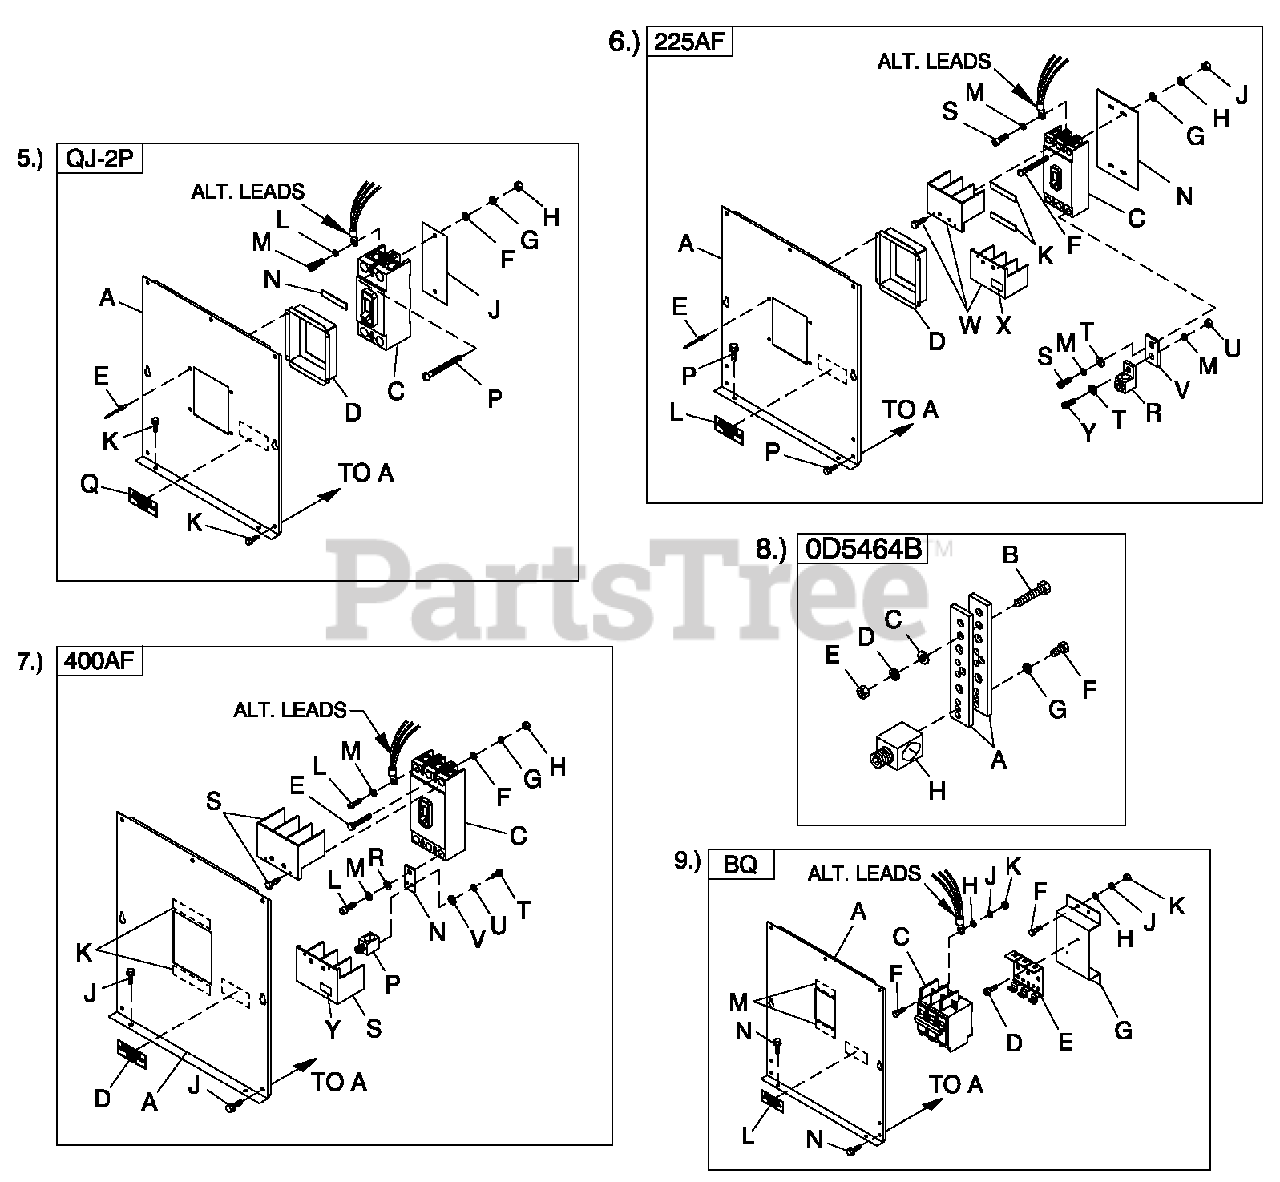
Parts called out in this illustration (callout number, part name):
9	UL CIRCUIT BREAKER (BQ)
A	COVER QJ 2P FRM CB
C	CB 0225A 240V 2P S QJ22
D	COVER QJ 2P CB DISH
E	RIVET POP.125X.275SS
F	WASHER FLAT 1/4-M6 ZINC
G	WASHER LOCK M6-1/4
H	NUT HEX 1/4-20 STEEL
J	INSULCB2P QJ
K	SCREW THF M6-1 X 16 N WA Z/JS
L	WASHER LOCK 3/8
M	SCREW SHC 3/8-16 X 3/4 G8.8 NZ
N	TAPE ELEC 1/2 FOAM (AS REQ' D)
P	SCREW RHM 1/4-20X3
Q	DECAL CUSTOMER CONNECT INSI DE
A	COVER CBC2-C4 225AF
C	CIRCUIT BREAKERS 200A FRAME
D	COVER CB DISH 225AF
E	RIVET POP .125X .275 SS
F	SCREW RHM #8-32X3-1/4
G	WASHER FLAT #8 ZINC
H	WASHER LOCK #8-M4
J	NUT HEX #8-32 STEEL
K	TAPE ELEC 1/2 FOAM
L	DECAL CUSTOMER CONNECT INSI DE
M	WASHER LOCK M8-5/16
N	INSULATOR CB225AF
P	SCREW THF M6-1 X 16 N WA Z/JS
R	LUG SLDLSS 300 MCM-6 AL/CU
S	SCREW SHC M8-1.25X20G8
T	WASHER FLAT 5/16-M8 ZINC
U	NUT HEX M8-1.25 G8 CLEARZINC
V	BUS BAR 200A LUG A DAPTOR
W	TERMINAL COVER CB
X	DECAL TERMINAL SHOCK HZ D BI
Y	SCREW SHC M8-1.25 X 25 G12.9
A	COVER CBC2-C4 400AF
C	CIRCUIT BREAKERS 400A FRAME
D	DECAL CUSTOMER CONNECT INSI DE
E	SCREW RHM 10-32X4
F	WASHER FLAT #10 ZINC
G	WASHER LOCK #10
H	NUT HEX #10-32 STEEL
J	SCREW THF M6-1 X 16 N WA Z/JS
L	SCREW SHC M10-1.5X 25 G12.9
M	WASHER LOCK M10
N	BUS BAR CB A DAPTER 225-400 A
P	LUG SL DLSS 600/250-1/0 X 1/4-28
S	TERM COVER CB
T	SCREW HHC 1/4-28 X 1/2 G5
U	WASHER LOCK M6-1/4
V	WASHER FLAT 1/4-M6 ZINC
Y	DECAL TERMINAL SHOCK HZ D BI
A	BUS BAR NEUTRAL BLOCK 390
B	SCREW HHC M8-1.25X 45 G8.8 FT
C	WASHER FLAT 5/16-M8 ZINC
D	WASHER LOCK M8-5/16
E	NUT HEX M8-1.25G8YELCHR
F	SCREW HHC 1/4-28 X 3/4 G5
G	WASHER LOCK 1/4-M6SS
H	LUG SL DLSS 600/250-1/0 X 1/4-28
A	COVER BQ CIR BREAKER CPL 3P
C	CB 0125A 2P 240V S BQ2 LL
D	SCREW PHTT M4-0.7 X 10 ZYC
E	BRKTCBMTG BACK
F	SCREW RHM #10-32X3/4
G	BRKT BQCBSTANDOFF
H	WASHER FLAT #10 ZINC
J	WASHER LOCK #10
K	NUT HEX #10-32 STEEL
M	TAPE ELEC 1/2 FOAM
N	SCREW THF M6-1 X 16 N WA Z/JS
